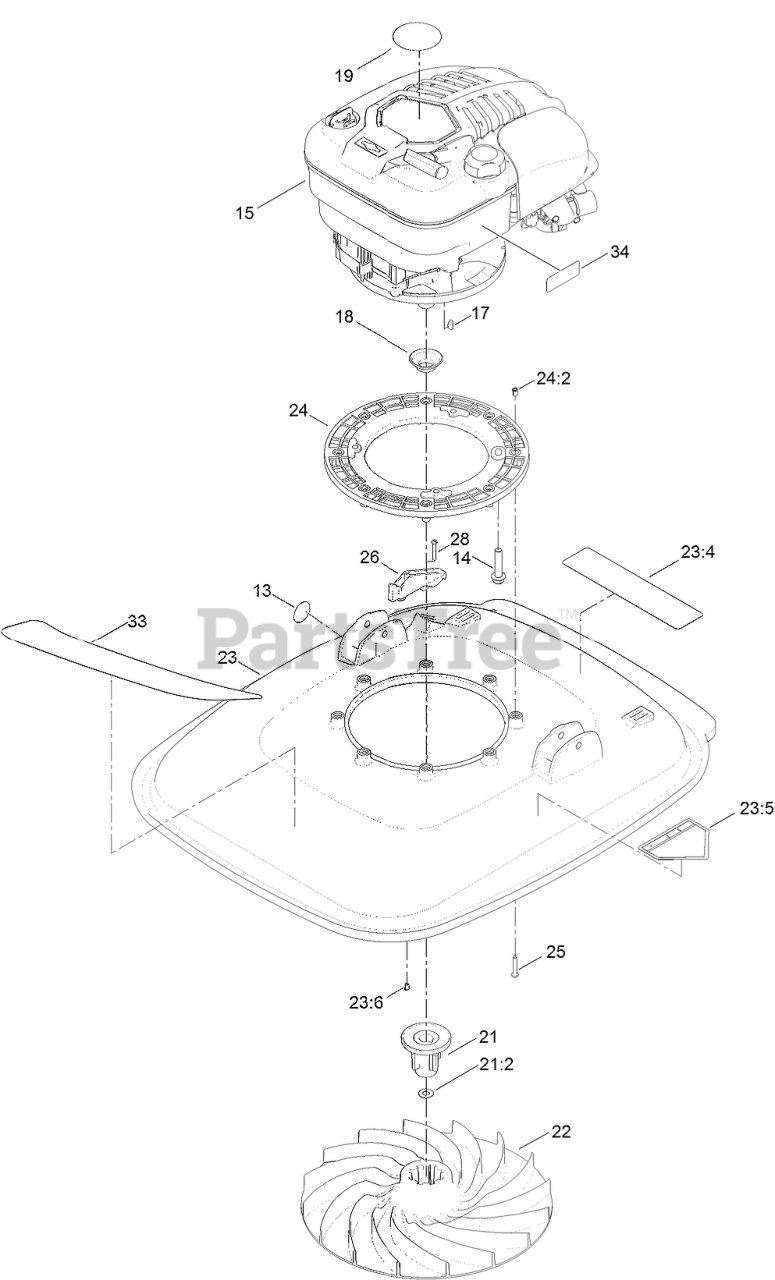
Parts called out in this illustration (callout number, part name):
13	DECAL
14	SCREW-TAPTITE
15	ENGINE-HONDA
17	KEY-WOODRUFF
18	PROTECTOR-SEAL, OIL
19	DECAL-ENGINE
21	DRIVE AND SPACER ASM
21:2	WASHER-PLAIN
22	IMPELLER
23	DECK ASM
23:4	DECAL-WARNING
23:5	DECAL-DANGER
23:6	INSERT
24	FRAME-ENGINE
24:2	INSERT-BRASS
25	SET-SCREW
26	BRACKET
28	SCREW
33	DECAL-HOVER PRO, 550 SERIES
34	DECAL-WARNING, ETHANOL
